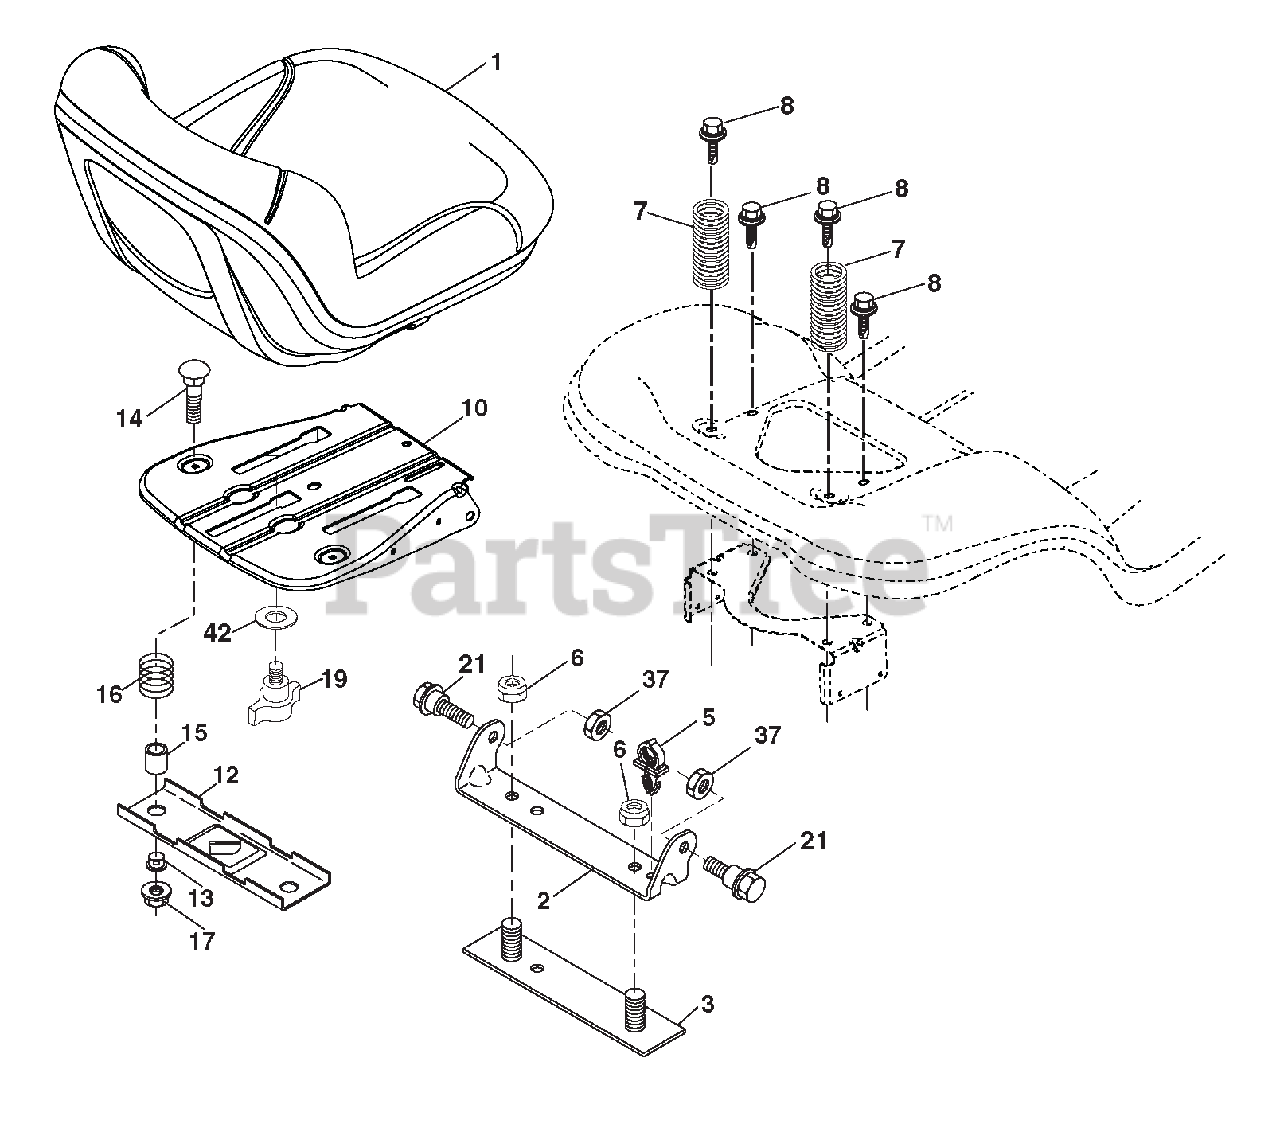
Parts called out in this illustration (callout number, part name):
2	BRACKET.PIVOT.FENDER.2002
3	STRAP ASM.FENDER.94
5	CLIP.PUSH-IN.HINGED
6	Locknut, Washer Insert 3/8-16
7	SPRING.SEAT.CPRSN.2.250.BLK.ZI
8	BOLT.5/16-18UNCX3/4 W/SEMS.BLK
10	PAN, SEAT
12	BRACKET.MNT.OPC.SW.SEAT.TEX LT
13	BUSHING.SNAP.BLK.NYL..50 ID.
14	BOLT.RDHD.SHT.NK.1/4-20X1-1/2
15	SPACER.SPLIT..28X.96.YEL.ZINC
16	SPRING.CPRSN.PLATE.SW.1.310.GA
17	NUT.LOCK.1/4 LGE.FLG.GR.5.ZINC
19	KNOB.SEAT ADJ.3/8-16"TEX
21	BOLT.SHLD.5/16-18 UNC-2A.BLK D
37	Locknut, Washer Insert 5/16-18
42	WASHER.CUP.SEAT.TEX LT
